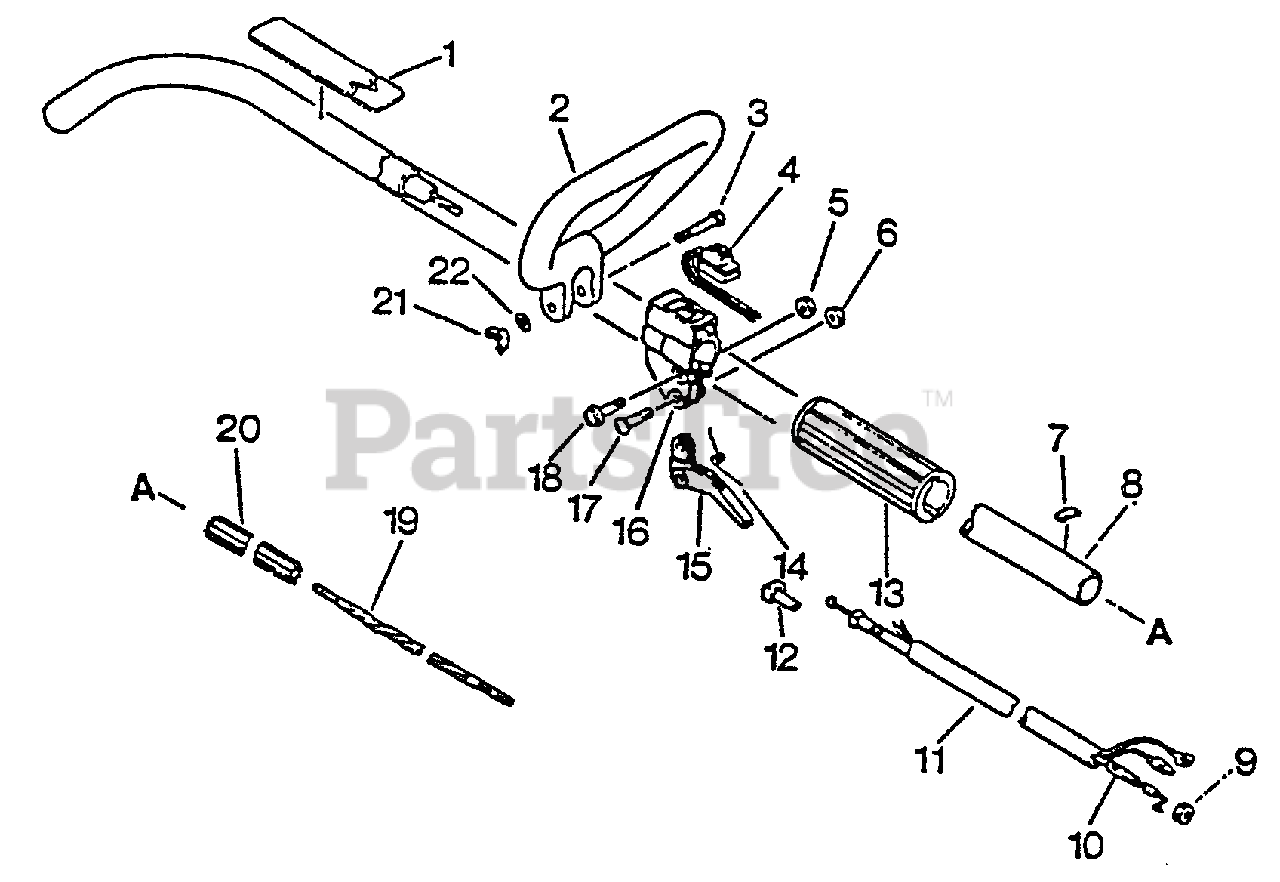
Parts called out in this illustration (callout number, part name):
1	LABEL - CAUTION
2	HANDLE
3	BOLT - 6X40
4	IGNITION SWITCH ASSY
6	LOCKNUT - 5
7	LABEL - ALIGNMENT
8	PIPE, MAIN
10	CABLE, THROTTLE
11	TUBE - VINYL
12	GUIDE, CABLE
13	GRIP, HANDLE
14	SPRING, TRIGGER
15	TRIGGER, THROTTLE
16	BRACKET, THROTTLE CONTROL
17	SCREW - 5X30
18	SCREW - 5X28
19	DRIVESHAFT - FLEXIBLE
20	LINER - FLEXIBLE
21	WINGNUT - 6
22	WASHER - 6
